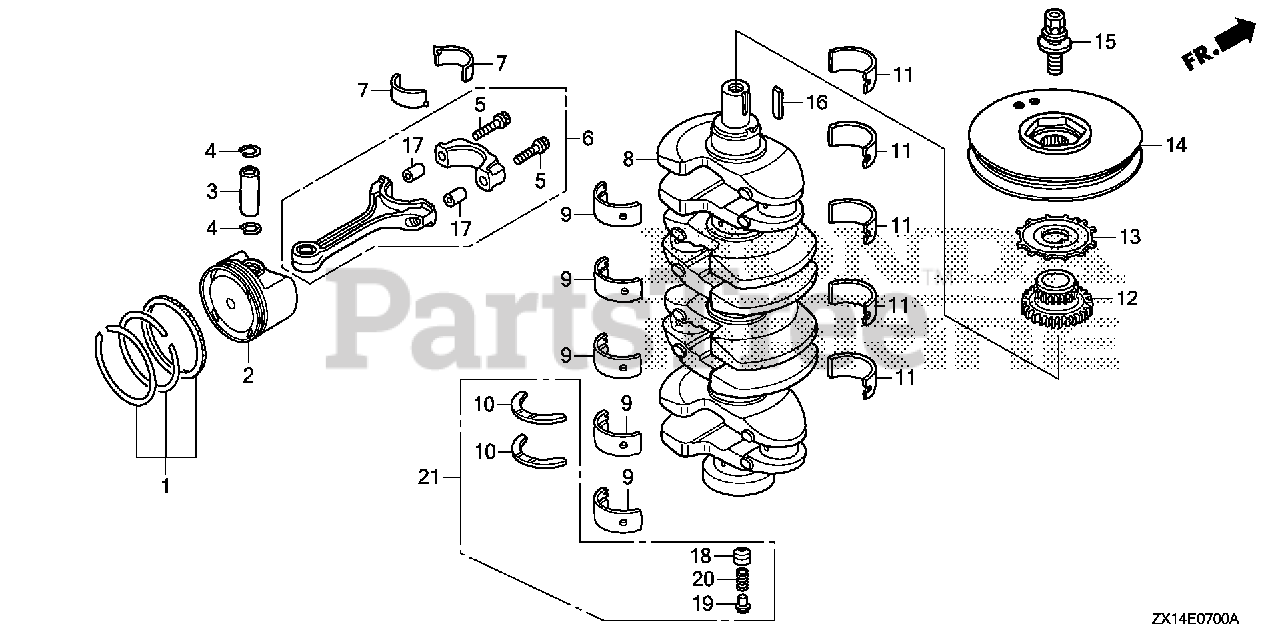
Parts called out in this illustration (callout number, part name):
1	RING SET, PISTON (STD)
3	PIN, PISTON
4	CLIP, PISTON PIN
5	BOLT, CONNECTING ROD
5	BOLT, CONNECTING ROD (SOURCE: VINTAGE PARTS INC.)
6	ROD, CONNECTING
7	BEARING A, CONNECTING ROD (BLUE)
7	BEARING B, CONNECTING ROD (BLACK)
7	BEARING C, CONNECTING ROD (BROWN)
7	BEARING D, CONNECTING ROD (GREEN)
7	BEARING E, CONNECTING ROD (YELLOW)
7	BEARING F, CONNECTING ROD (PINK)
7	BEARING G, CONNECTING ROD (RED)
8	CRANKSHAFT
9	BEARING A, MAIN (UPPER) (BLUE) (DAIDO)
9	BEARING B, MAIN (UPPER) (BLACK) (DAIDO)
9	BEARING C, MAIN (UPPER) (BROWN) (DAIDO)
9	BEARING D, MAIN (UPPER) (GREEN) (DAIDO)
9	BEARING E, MAIN (UPPER) (YELLOW) (DAIDO)
9	BEARING F, MAIN (UPPER) (PINK) (DAIDO)
10	WASHER, THRUST
11	BEARING A, MAIN (LOWER) (BLUE) (DAIDO)
11	BEARING B, MAIN (LOWER) (BLACK) (DAIDO)
11	BEARING C, MAIN (LOWER) (BROWN) (DAIDO)
11	BEARING D, MAIN (LOWER) (GREEN) (DAIDO)
11	BEARING E, MAIN (LOWER) (YELLOW) (DAIDO)
11	BEARING F, MAIN (LOWER) (PINK) (DAIDO)
12	SPROCKET, CHAIN DRIVE
13	PLATE, CRANK PULSER
14	PULLEY, CRANKSHAFT
15	BOLT-WASHER (16X49)
16	KEY (4.5X21)
17	PIN, DOWEL (10X12)
18	RETAINER, SPRING
19	SEAT, SPRING (150)
20	SPRING, SUPPORT
21	WASHER KIT, THRUST (150)
